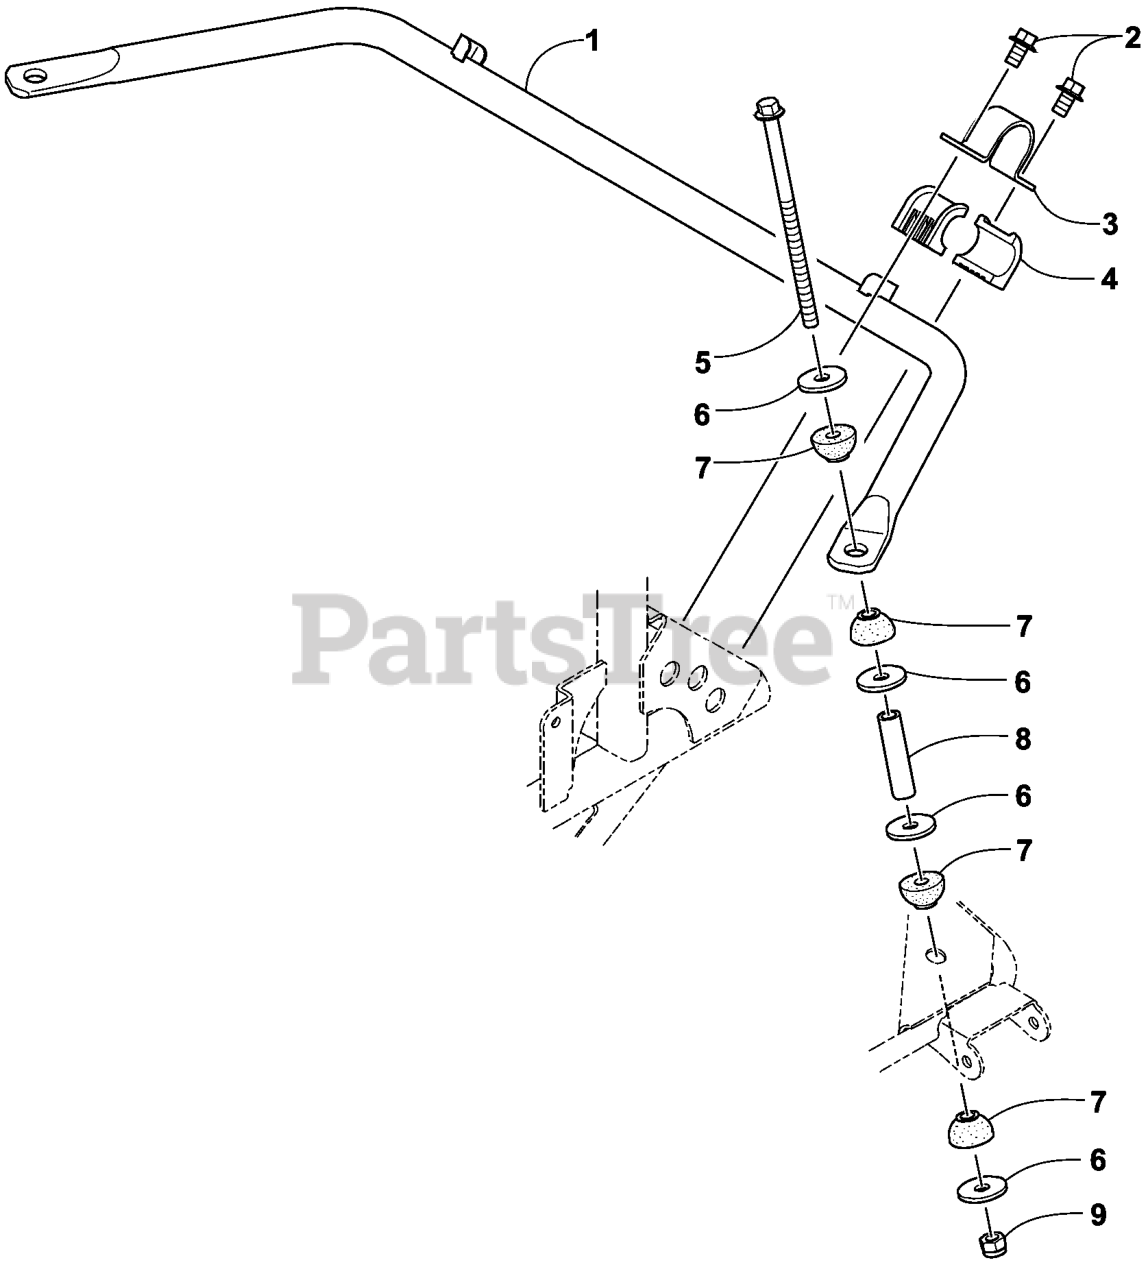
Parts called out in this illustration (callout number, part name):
1	SWAYBAR-REAR
2	SCREW-HFH
4	BUSHING-HALF, SWAYBAR
5	SCREW-HFH
6	WASHER-FLAT
7	BUSHING-SWAYBAR LINK
8	SPACER-SWAYBAR
